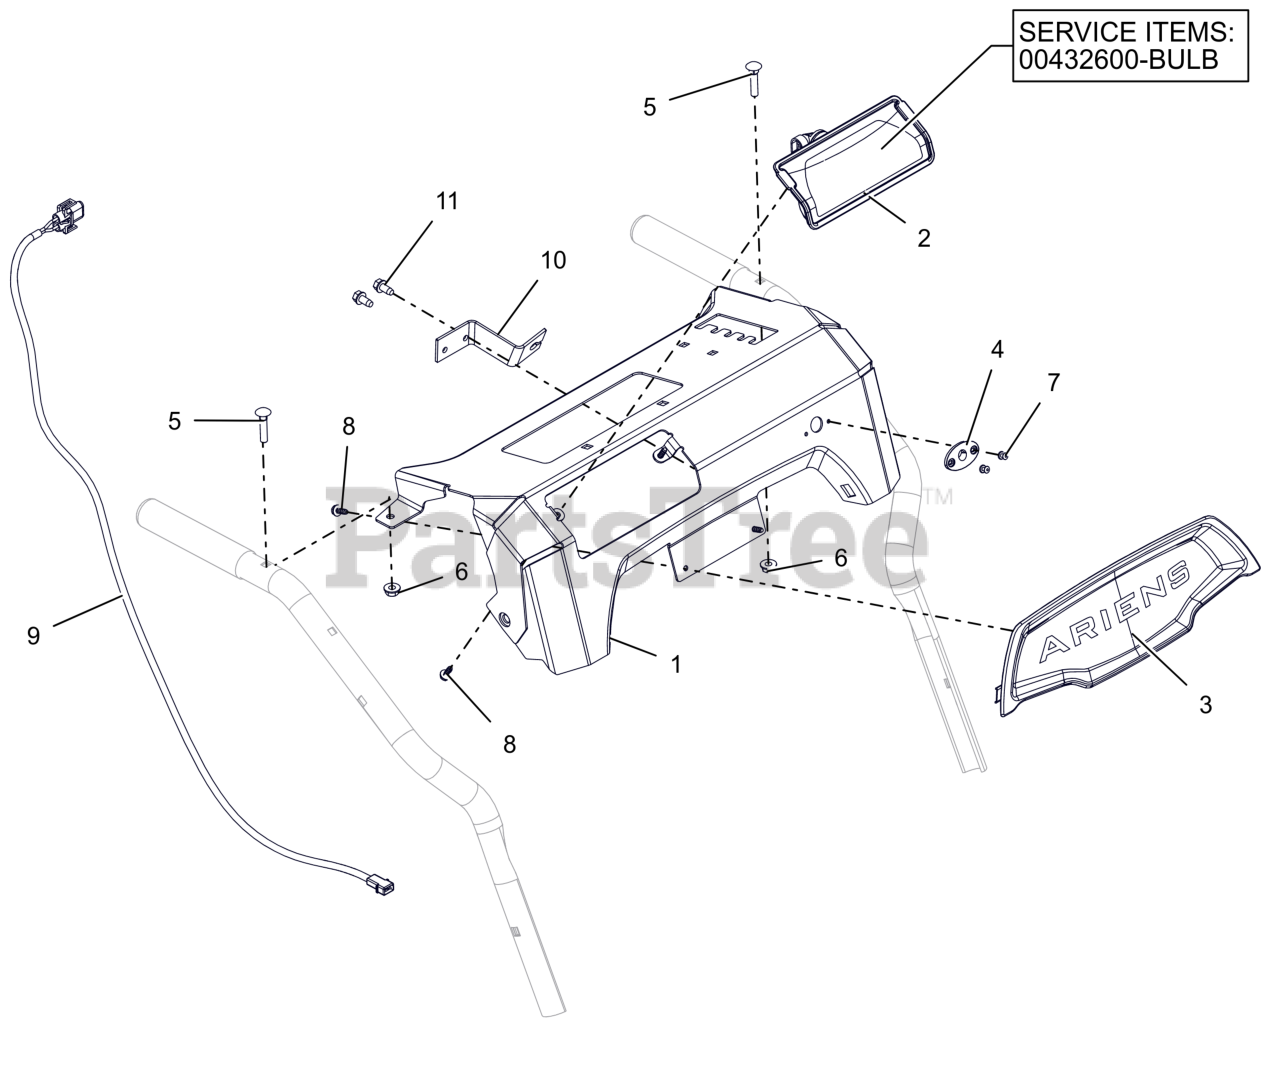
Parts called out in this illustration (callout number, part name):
1	CTRL PANEL W/DECAL-SM DASH DLX
2	HEADLIGHT ASY, HALO 20W 2SHOT
2	BULB, LIGHT-HALOGEN 20W
3	BEZEL, DASH - ARIENS SM DASH
4	BSHG, CHUTE CRANK
5	BLT-RDHDXLSQNK.25-20X1.25 G5ZC
6	NUT-LK-TOP-FLG .250-20 GF ZCC
7	RVT-POP #43 .125X.313 STL ZINC
8	SCR, PLASTIC #10X.50
9	HARNESS, LIGHT - COMPACT
10	ANCHOR, DEFLECTOR CABLE
11	SCR-TAP .25-20X.50 HWH ZCC
